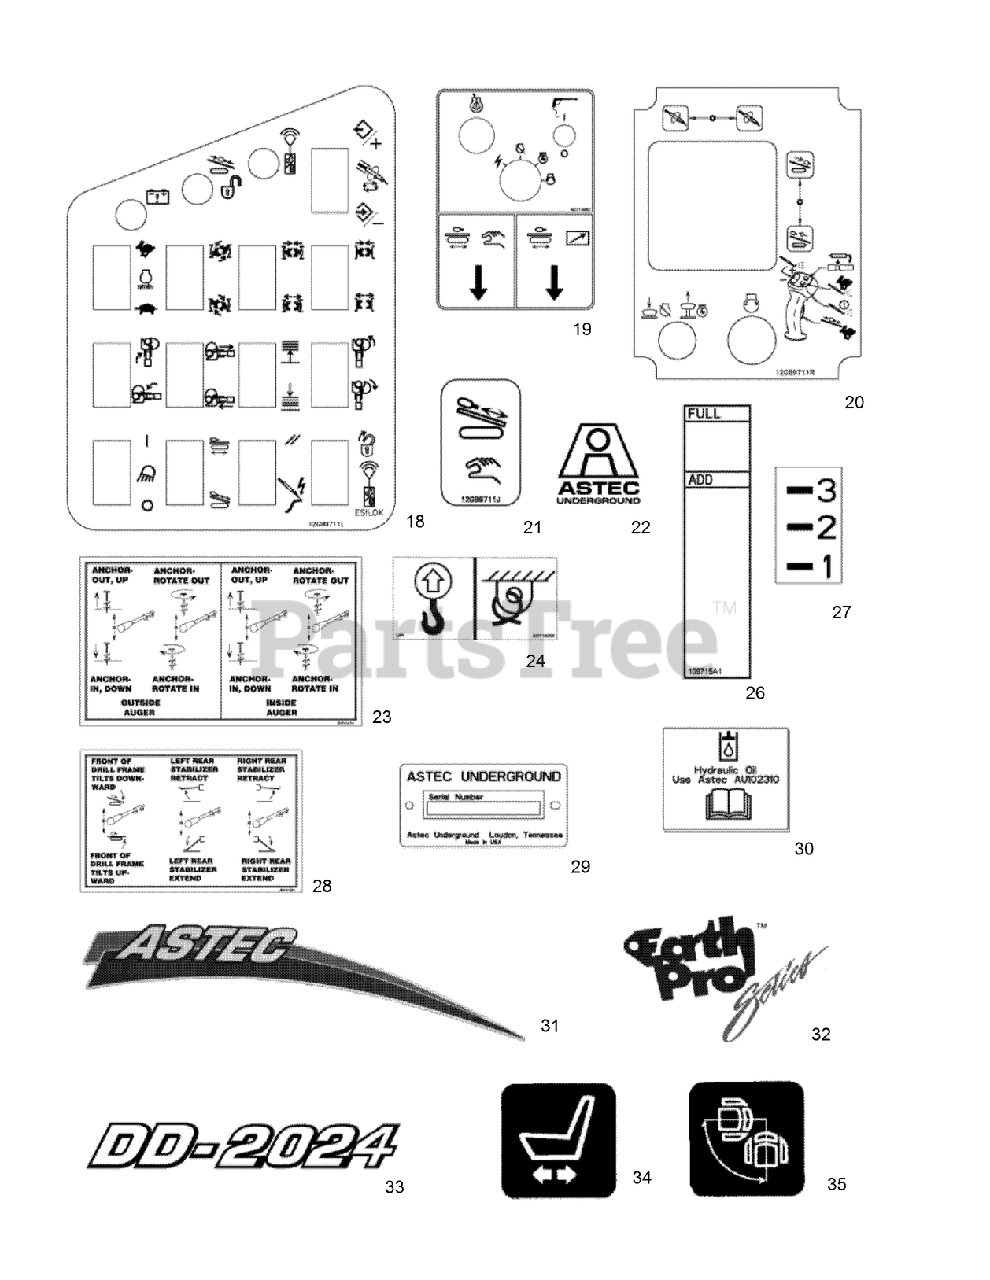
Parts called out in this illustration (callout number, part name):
19	OVERLAY - Rear Controls
20	DECAL - Joystick Overlay
21	DECAL - Remote Plug
22	DECAL - A, Astec Underground
23	DECAL - Auger Control Functions
24	DECAL-Tie Down / Lift Hook
26	DECAL - Hydraulic Fluid Level
27	DECAL - Row Selector
28	DECAL - Tilt and Stabilizer Lever Controls
29	PLATE - Serial Number
30	DECAL - Hydraulic Fluid.
31	DECAL - Astec, Red and Blue Pattern
32	DECAL - Earth Pro, Medium Size
33	DECAL - DD-2024
34	DECAL - Seat Fore/Aft
35	DECAL - Seat Pivot In/Out
